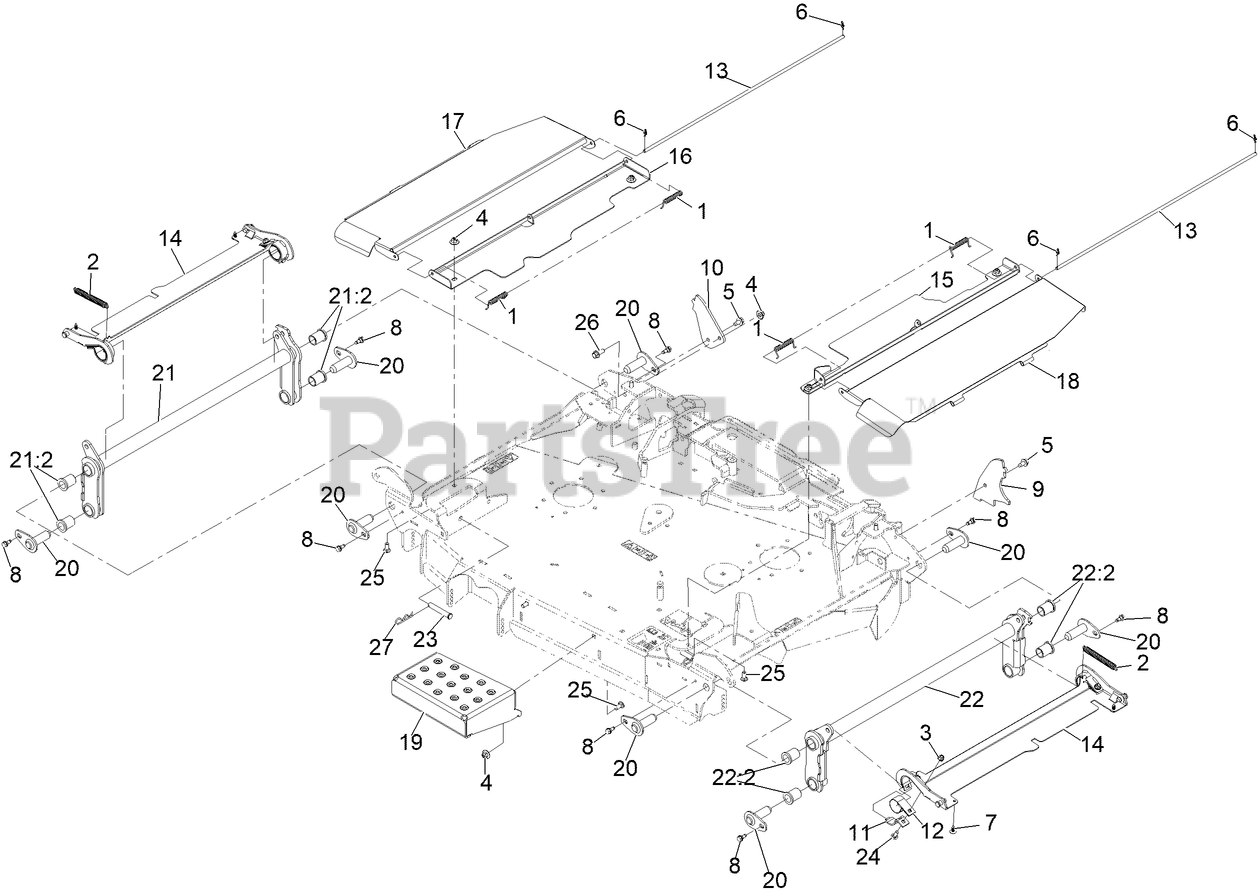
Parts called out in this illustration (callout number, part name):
1	SPRING-TORSION
3	NUT-HF, NI
4	Nut-Nyloc 3/8-16 Flg
5	SCREW-HWH
6	PIN-COTTER, LOCKING
7	PLUG-PLASTIC
8	SCREW-SHOULDER
9	BRACKET-DECK STOP, LH
10	BRACKET-DECK STOP, RH
11	PLATE-RETAINER, BEARING
12	BEARING-STRAP, NYLON
13	COVER-ROD, PIVOT
14	COVER-WING
15	SHIELD-CENTER, LH
16	SHIELD-CENTER, RH
17	Panel-Shield Hinge, LH
18	Shield-Center, RH
19	Panel-Step
20	ASM-DECK PIN
21	ASM-FOLS ARM, RH
21:2	BUSHING-FLANGED
22	ASM-FOLD ARM, LH
22:2	BUSHING-FLANGED
23	PIN-CLEVIS
24	SCREW-CARR
25	BOLT-CARR
26	SCREW-HHF 3/8-16 X 1
27	PIN-HAIR
